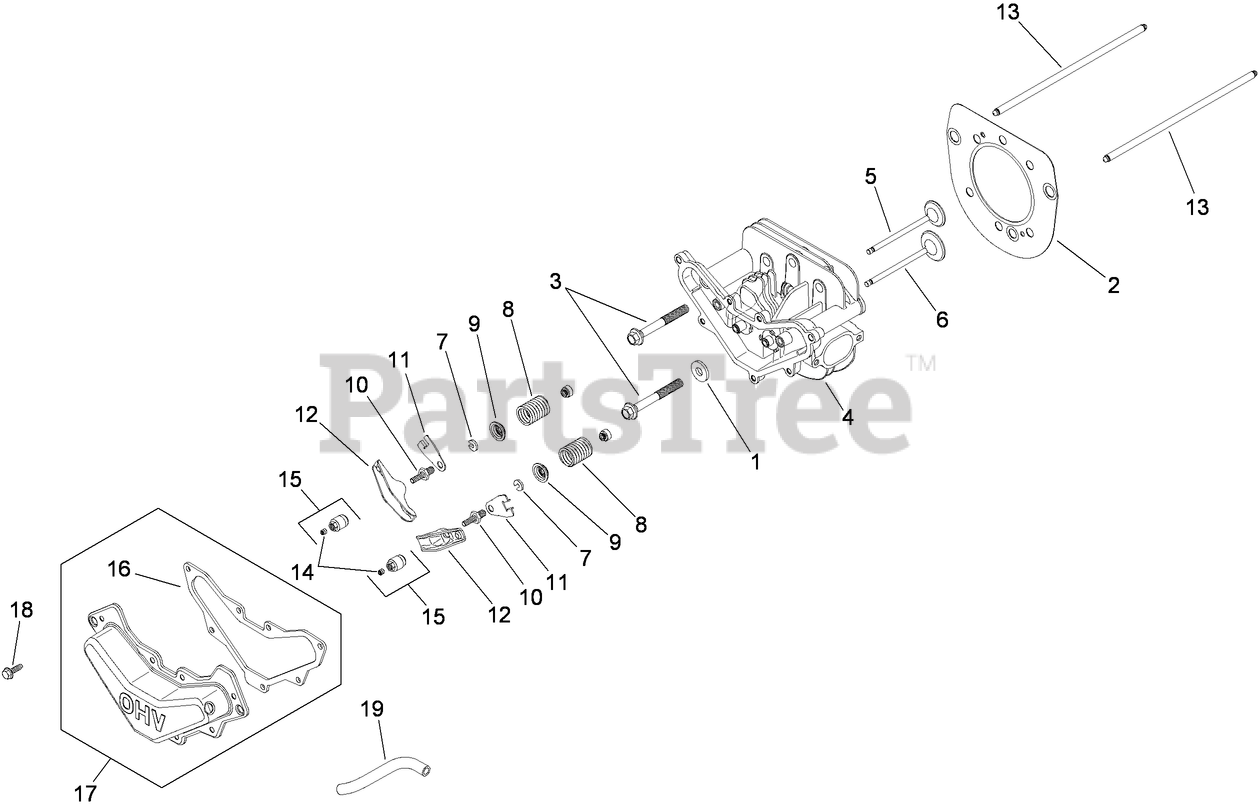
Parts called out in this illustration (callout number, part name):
1	Washer-Flat (1/2)
2	Cylinder Head Gasket Kit (Includes 2, 13-14)
3	Screw-Flange, Hex (M10x1.5x37)
4	CYLINDER HEAD KIT
5	Valve-Exhaust
6	Valve-Intake
7	Lock-Retainer
8	Spring-Valve
9	Cap-Spring, Valve
10	STUD-ROCKER
11	Plate-Guide, Push Rod
12	Arm-Rocker
13	Rod-Push
14	Screw-Set
15	ROCKER PIVOT ASM (INCLUDES REF 6)
16	Gasket-cover, valve
17	Valve Cover Kit (Includes 2)
18	SCREW-HHFTF (M6X1.0X20)
19	HOSE-BREATHER
